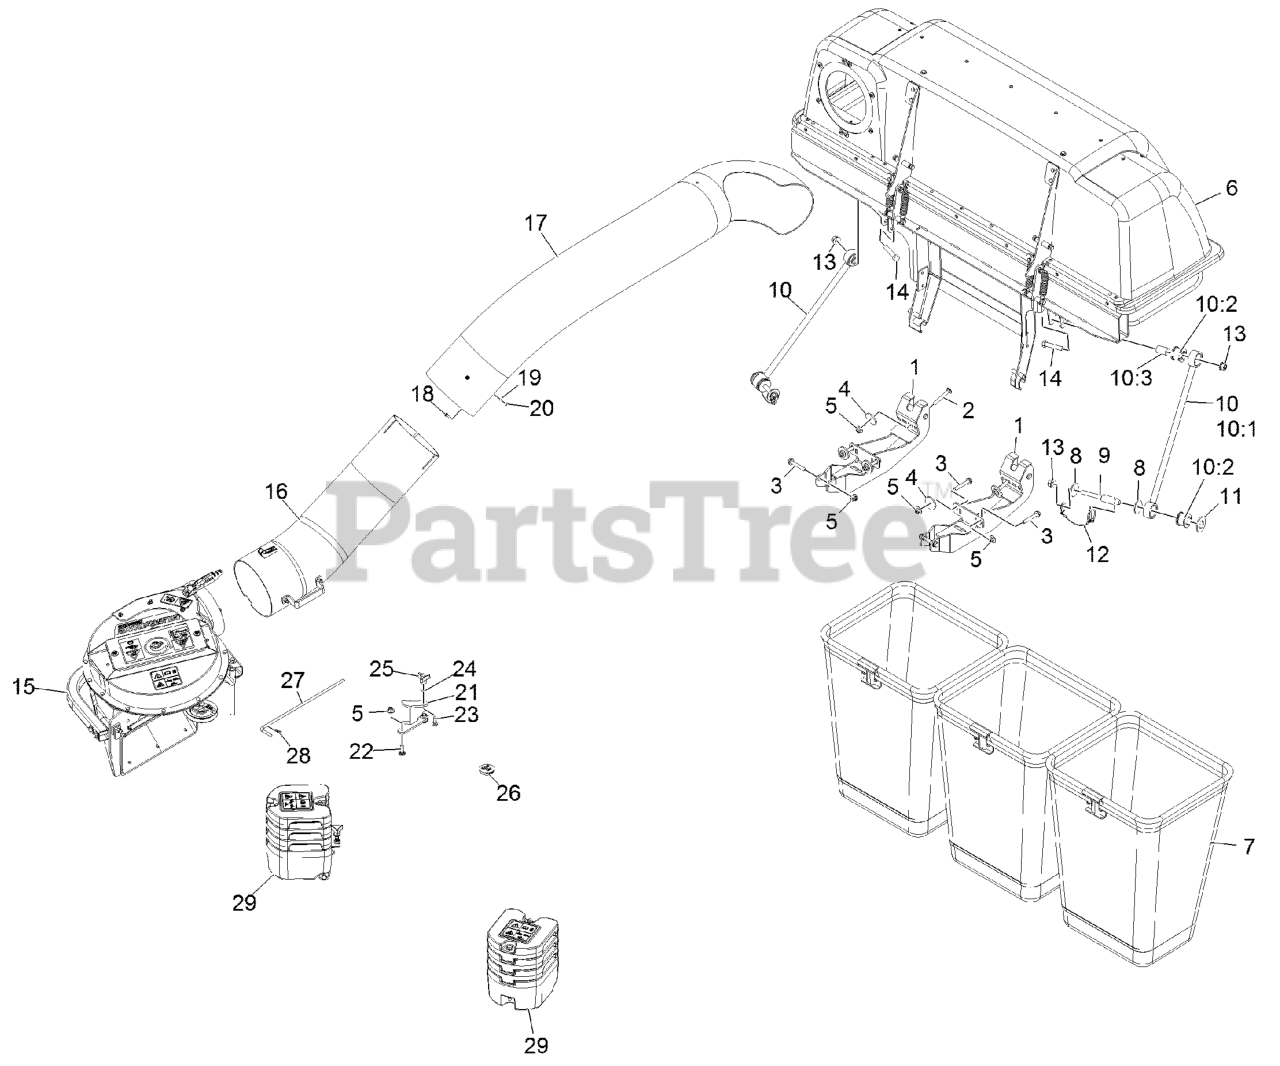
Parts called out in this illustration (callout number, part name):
1	MOUNT-BAGGER, LOWER
2	SCREW-CARR
3	Screw-HHF
4	Washer-Plain
5	Nut-Nyloc 3/8-16 Flg
7	BAG AND FRAME ASM
8	WASHER-THRUST
9	PIN-BAGGER BRKT
10	SUPPORT ROD ASM
10:1	Wld,Panhard Rod
10:2	BUSHING-RUBBER
11	Washer-Flat
12	PIN-MOUNT, BAGGER
13	Nut-Lock 1/2-13
14	SCREW-HH
15	ASM, BLOWER LARGE - SVC O
16	LOWER TUBE ASM
17	TUBE-UPPER
18	SCREW-HWH
19	WASHER-FLAT
20	NUT-LOCK, NI
21	BRACKET,BELT COVER
22	Bolt-Carriage 3/8-16 X 1 1/4
23	BOLT-CARR
24	RING-RETAINING, BOLT
25	KNOB-3 PRONG
26	PLUG, BLACK NYLON 1.75
27	PIN,CHUTE PIVOT
28	PIN-COTTER
29	ASM-Caster Weight
